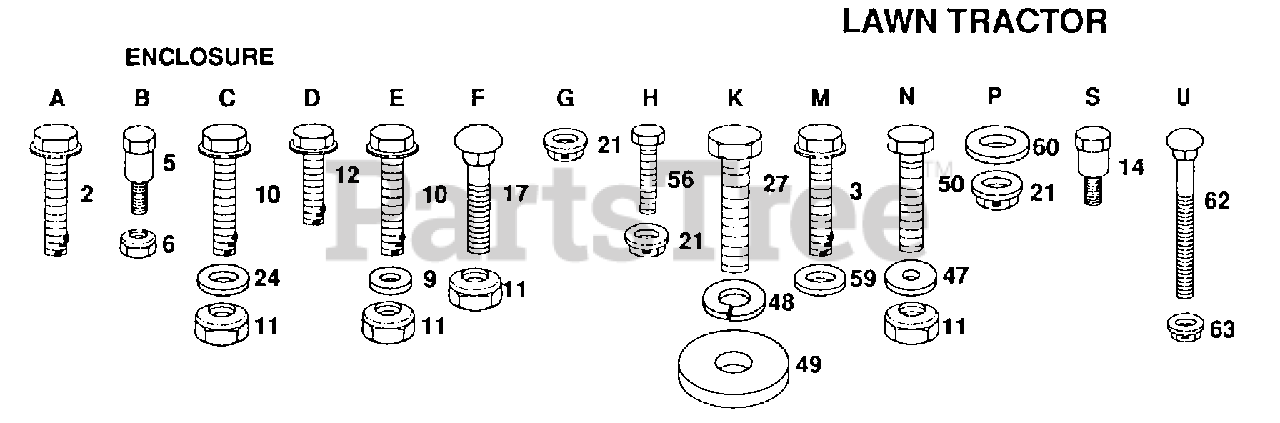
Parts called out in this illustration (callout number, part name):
2	SCREW
3	SCREW GTV
9	WASHER
12	SCREW LT
17	BOLT
21	PAL NUT LT
24	WASHER
27	BOLT
47	WASHER
48	LOCKWASHER
49	WASHER
50	BOLT
56	SCREW SPECIAL
59	WASHER
60	WASHER PM
62	BOLT
